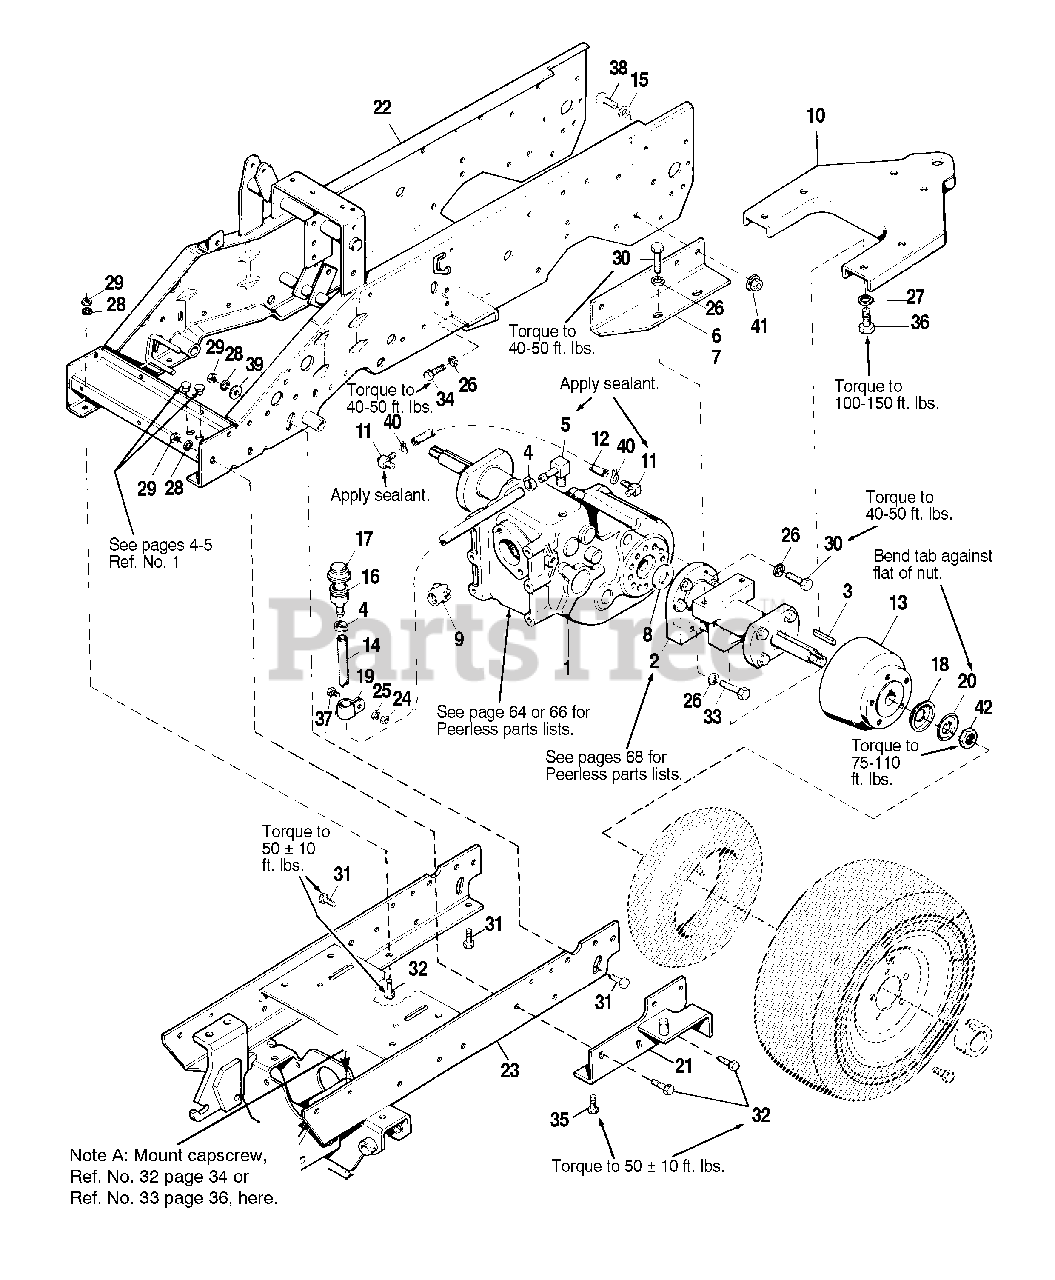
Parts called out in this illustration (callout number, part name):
1	TRANSAXLE, Peerless, 2 Speed, 20 HP Only
1	TRANSAXLE, Peerless, 1 Speed, 18 HP Only
2	AXLE, Housing Assy., Peerless
3	KEY, 5/16 x 5/16 x 2-1/2
4	CLAMP, Hose
5	FITTING, Hose, 90°.
6	SUPPORT, Transmission, RH
7	SUPPORT, Transmission, LH
8	SPACER, Axle
9	GEAR, Bevel
11	FITTING, Elbow
12	HOSE, Fluid Level
13	DRUM, Brake
14	HOSE, Fill, 1/2 I.D.
15	WASHER, Plain
16	NECK, Filler
17	CAP, Filler
18	RETAINER, Hub Cap
19	CLAMP, Insulated
20	RETAINER, Washer
21	BRACKET ASSY., Power Steering Cylinder
22	FRAME ASSY., Rear
23	FRONT FRAME ASSY.
24	NUT, Hex, 1/4-20
25	LOCKWASHER, 1/4
26	LOCKWASHER, 1/2
27	LOCKWASHER, 5/8
28	LOCKWASHER, 7/16
29	NUT, Hex, 7/16-14
30	CAPSCREW, Hex Hd., 1/2-13 x 1-1/2
31	CAPSCREW, Hex Hd., 7/16-14 x 1, Gr. 5
32	CAPSCREW, Hex Hd., 7/16-14 x 1-1 /4, Gr. 5
33	CAPSCREW, Hex Hd., 1 /2-13 x 2
34	CAPSCREW, Hex Hd., 1/2-13 x 1-1/4
35	CAPSCREW, 7/16-14 x 1-1/2
36	CAPSCREW, Hex Hd., 5/8-11 x 1-1/4
37	CAPSCREW, Hex Hd., 1/4-20 x 3/4
38	CAPSCREW, Hex Hd., 7/16-14 x 1-1/4
39	WASHER, Plain, 1/2
40	CLAMP, SAE #6
41	NUT, Hex, Flange, 7/16-14
42	NUT, Hex, Jam Centerlock, 1-14
